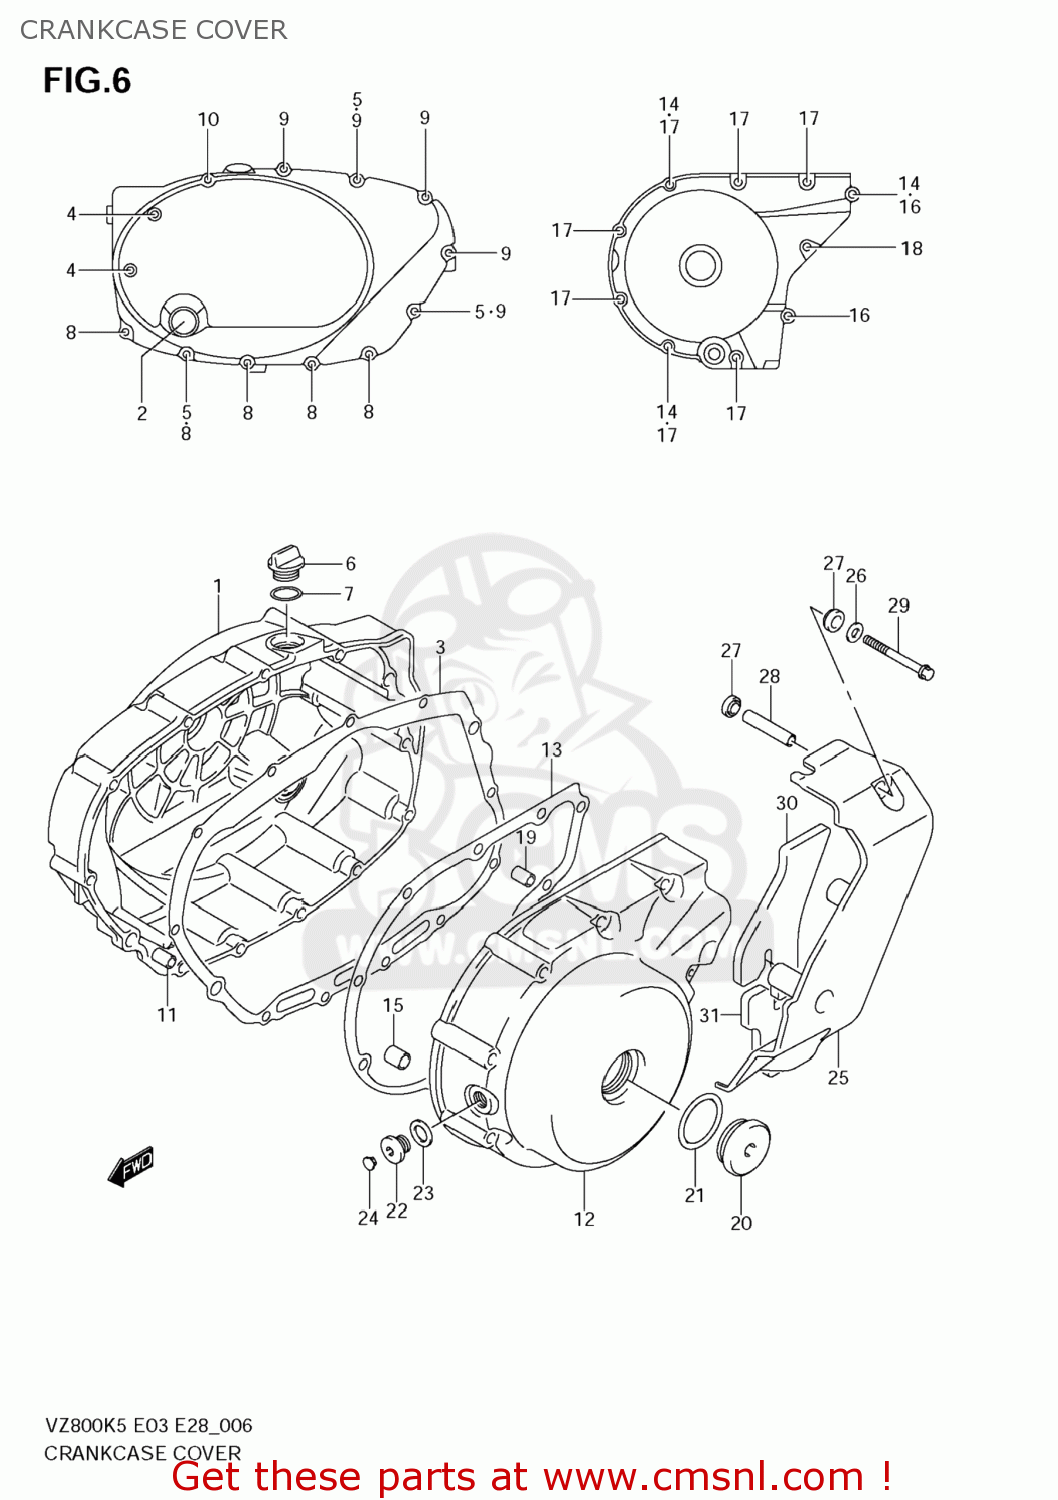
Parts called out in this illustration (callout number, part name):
1	COVER,CLUTCH
2	LENS,OIL LEVEL CHECK
3	GASKET,CLUTCH COVER (NAS)
4	BOLT(6X105)
5	GASKET(5.8X13X1.2) (NAS)
6	PLUG,ENGINE OIL FILLER
7	O RING(D:3.1,ID:16.8)
8	BOLT(6X30)
9	BOLT(6X50)
10	BOLT(6X85)
11	PIN
12	COVER,GENERATO
13	GASKET,GENERATOR COVER (NAS)
14	GASKET(5.8X13X1.2) (NAS)
15	PIN(8.4X11X20)
16	BOLT(6X40)
17	BOLT(6X55)
18	BOLT(6X85)
19	PIN
20	Chrome Crankshaft Plug
21	O RING(D:3.1,ID:32.7)
22	PLUG,14X12
23	GASKET(13.8X18.8X4.8) (NAS)
24	CAP(OD:12)
25	COVER,SECONDARY DRIVE UNIT
26	WASHER(6.5X14X1.6)
27	WASHER(8.7X16X5)
28	SPACER(6.5X9X41.3)
29	BOLT(6X55)
30	CUSHION,SEC DR UNIT COVER NO.1
31	CUSHION,SEC DR UNIT COVER NO.2
